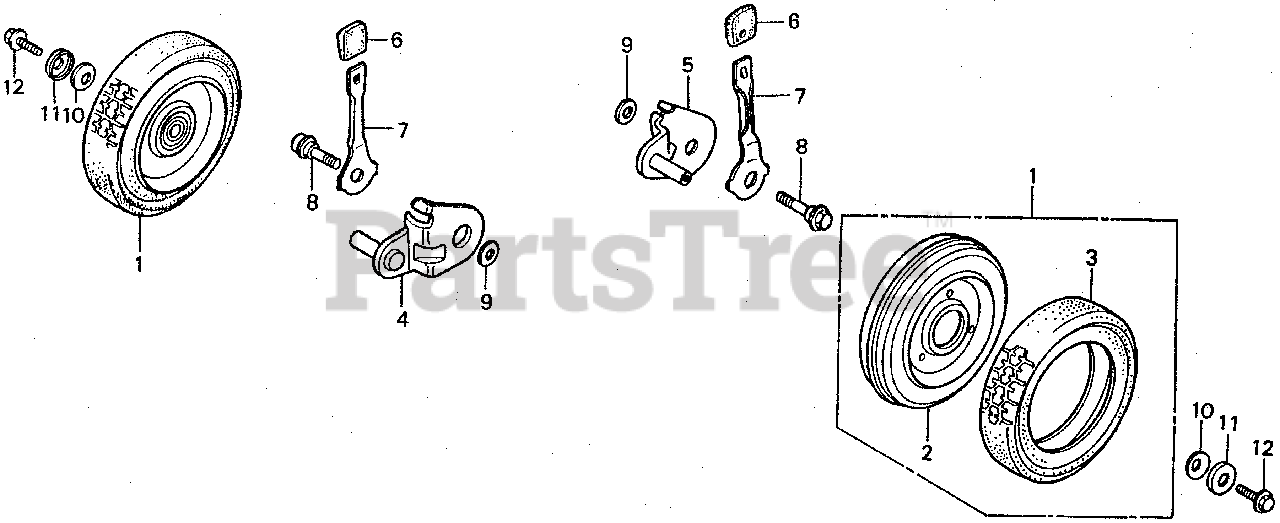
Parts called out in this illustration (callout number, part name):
1	WHEEL (NA USE ALT:06427-960-305)
2	WHEEL, RR. (NOT AVAILABLE)
3	TIRE (8X1.57)
4	ARM, R. FR. ADJUSTING (NOT AVAILABLE)
5	ARM, L. FR. ADJUSTING (NOT AVAILABLE)
6	GRIP, ADJUSTER
7	PLATE, FR. ADJUSTING
8	BOLT, RR. ADJUSTING ARM
9	WASHER (10MM) (NOT AVAILABLE)
10	WASHER, SPRING
11	WASHER, HANDLE CUSHION
12	BOLT, FLANGE (8X12)
